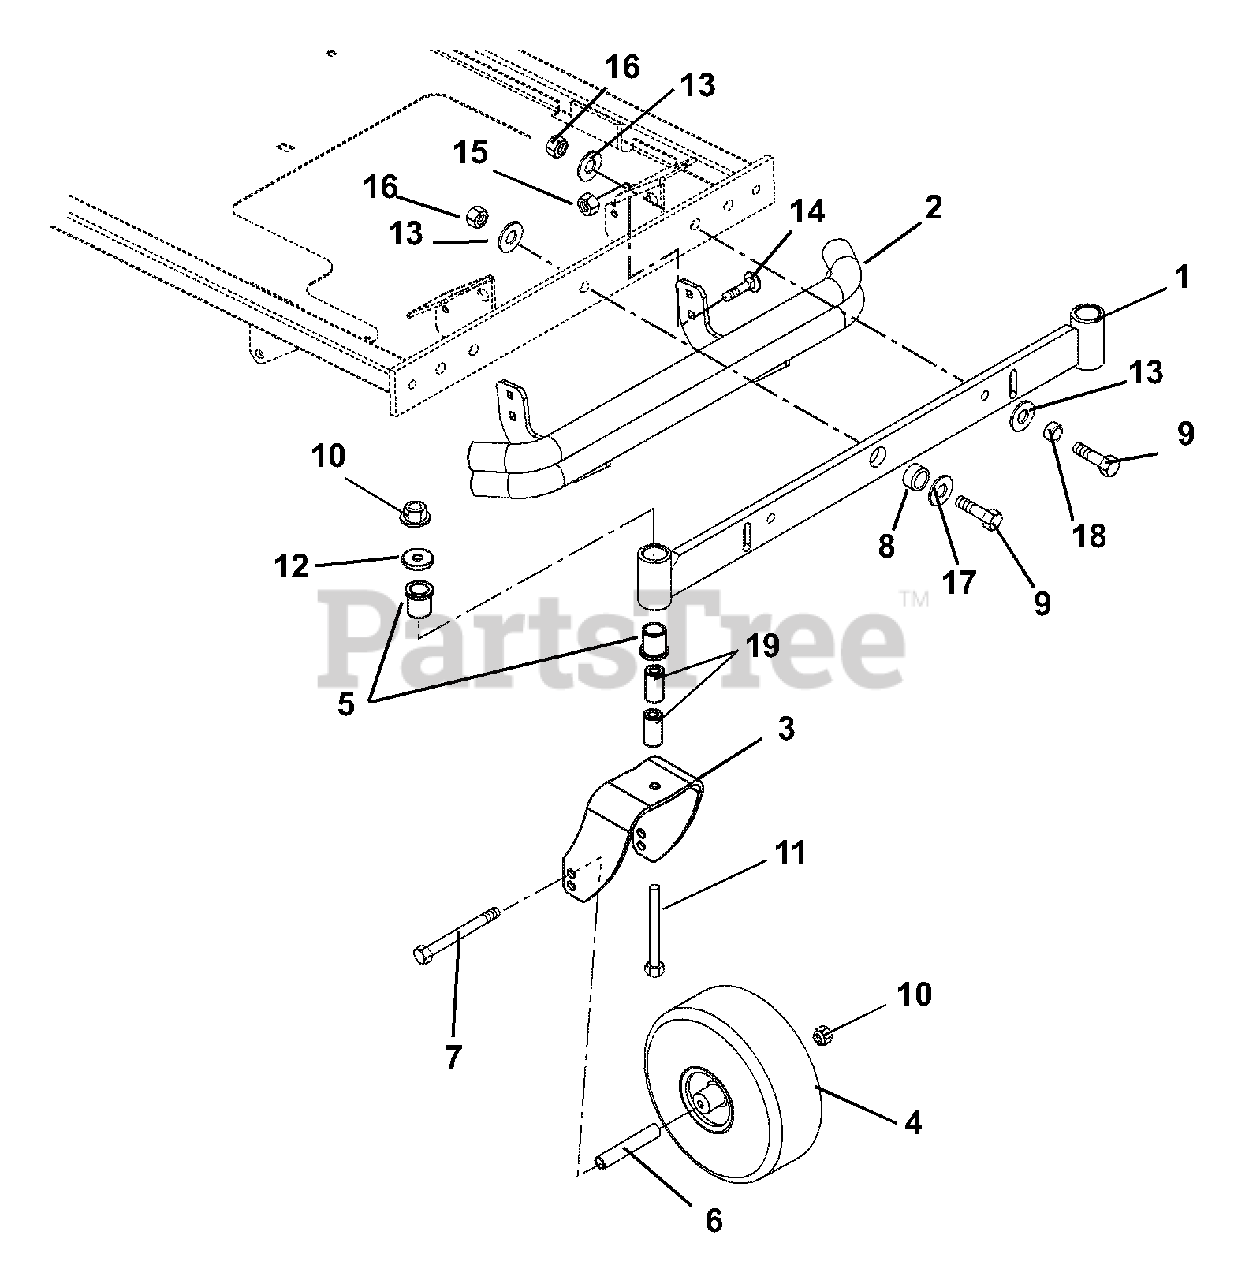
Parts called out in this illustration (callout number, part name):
1	Weldment, Front Axle
2	Bumper, Zoom
3	Fork, Caster
4	Assembly, Tire 4 x 11- 4 Ply
5	Bushing, Flange 1.00 x 1.25 x 1.50 x 1.50
6	Spacer, Rolled Wheel
7	Bolt, Hex .50-13 x 6.50 Grade 5
8	Bushing, Axle Pivot
9	Bolt-Hex .62-11X2.25 Grade 8
10	Nut, Locking Top Flange .50-13
11	Bolt, Hex .50-13 x 5.00 Grade 5
12	Washer, Flat Steel .511 x 1.441 x .125
13	Washer, Flat .64 x 1.81 x .25
14	Bolt, Round Head Square Neck .38-16 x 1.00 Grade 5
15	Nut .38-16 Flange Nyloc
16	Nut, Locking Nylon .625-11
17	Washer, Flat Steel .688 x 1.75 x .134
18	Spacer, .750 D x .558 Long
19	Spacer, Caster
